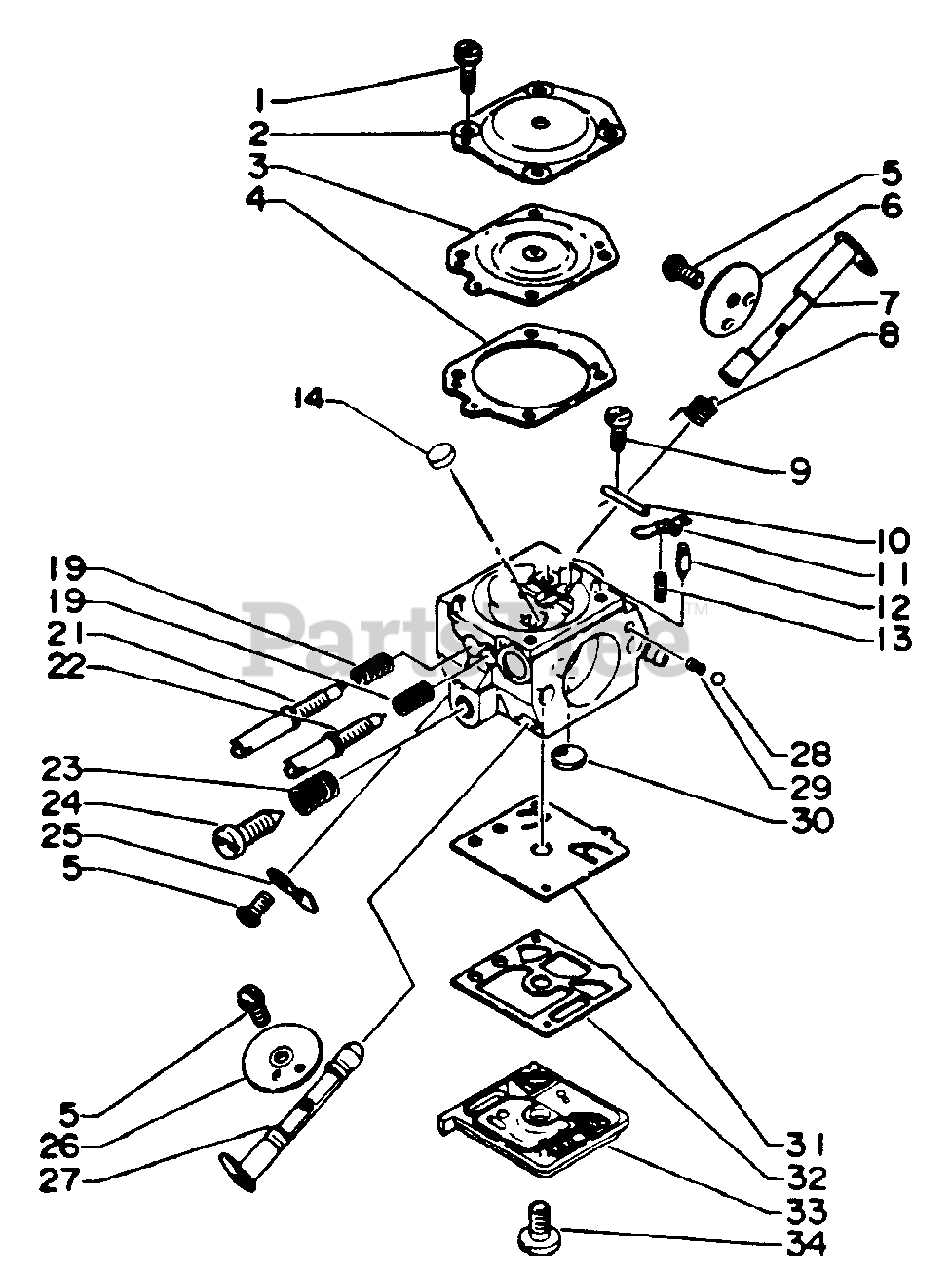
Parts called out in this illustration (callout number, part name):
2	COVER, DIAPHRAGM
3	DIAPHRAGM, METERING
4	GASKET, METERING
6	VALVE, THROTTLE
7	SHAFT, THROTTLE
8	SPRING, THROTTLE RETURN
9	SCREW, METERING LEVER PIN
10	PIN, METERING LEVER
11	LEVER, METERING
12	VALVE, INLET NEEDLE
13	SPRING, METERING LEVER
14	PLUG, WELCH
21	NEEDLE - HIGH SPEED
22	NEEDLE - LOW SPEED
23	SPRING, IDLE ADJUST
24	SCREW, IDLE ADJUST
25	STOP, THROTTLE
26	VALVE, CHOKE
27	SHAFT, CHOKE
28	BALL, CHOKE
30	STRAINER
31	DIAPHRAGM, PUMP
32	GASKET, PUMP
33	COVER, PUMP
34	SCREW, PUMP COVER
